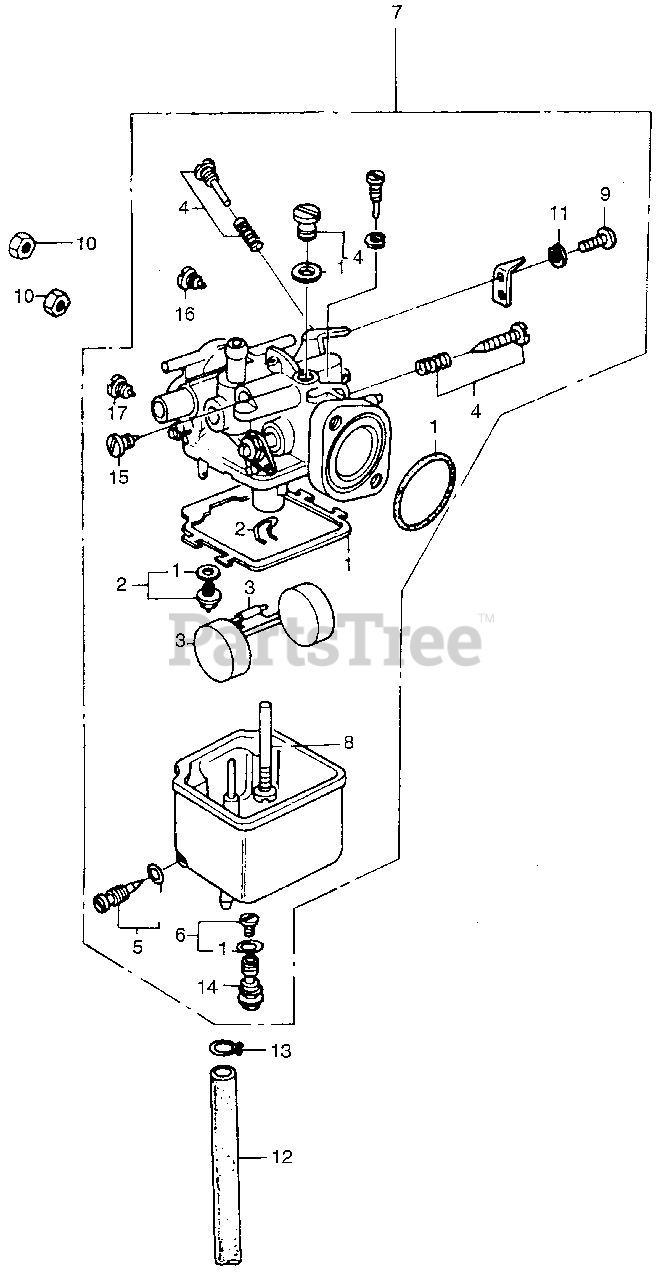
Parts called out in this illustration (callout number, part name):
1	GASKET SET, CARBURETOR (NOT AVAILABLE)
2	VALVE SET, FLOAT
4	SCREW SET A (NOT AVAILABLE)
5	SCREW SET, DRAIN (NOT AVAILABLE)
6	SCREW SET B (NOT AVAILABLE)
7	CARBURETOR ASSY. (NOT AVAILABLE)
8	NOZZLE, MAIN (NOT AVAILABLE)
9	SCREW, PAN (3X7) (NOT AVAILABLE)
10	NUT, HEX. (6MM)
11	WASHER, SPRING (3MM)
12	BULK HOSE, FUEL (3.5X3000) (3.5X240)
13	CLIP, TUBE (B7)
14	JET, MAIN (#95) (STD) (NOT AVAILABLE)
15	JET, PILOT (#48)
16	JET, MAIN AIR
17	JET, PILOT AIR
